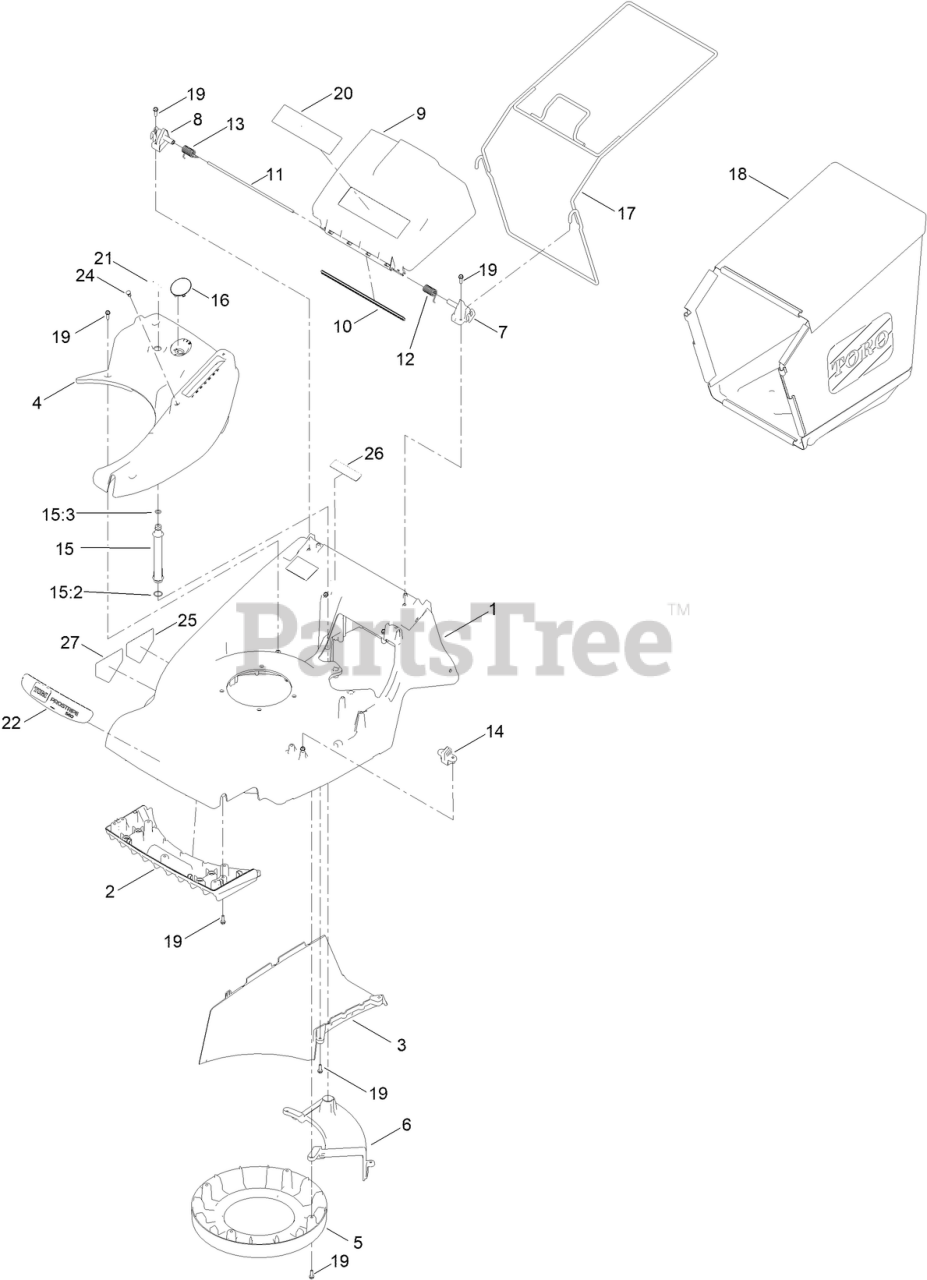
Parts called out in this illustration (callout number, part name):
1	HARRIER DECK ASSEMBLY
2	FINS-FRONT
3	PLATE-THROW
4	TRIM-TOP
5	COVER-BELT
6	COVER-BELT
7	MOUNT-DEFLECTOR, LEFT
8	DEFLECTOR MOUNT RIGHT
9	DEFLECTOR-REAR
10	DEFLECTOR-SEAL, REAR
11	ROD-DEFLECTOR
12	SPRING-DEFLECTOR, LEFT
13	SPRING-DEFLECTOR, RIGHT
14	ROD-SUPPORT
15	WASHPORT ASM, YELLOW
15:2	O-RING SEAL
15:3	O-RING SEAL
16	TOP TRIM PORT COVER
17	GRASSBAG-FRAME
18	FABRIC GRASSBAG, TORO
19	SCREW-TAPTITE
20	DECAL - SAFETY 60V
21	DECAL-QUICK WASH
22	DECAL - EPROSTRIPE 560
24	RIVET-PUSH, PLASTIC
25	DECAL-DANGER
26	DECAL-PROP 65, SHORT, TRILINGUAL
27	DECAL-DANGER
